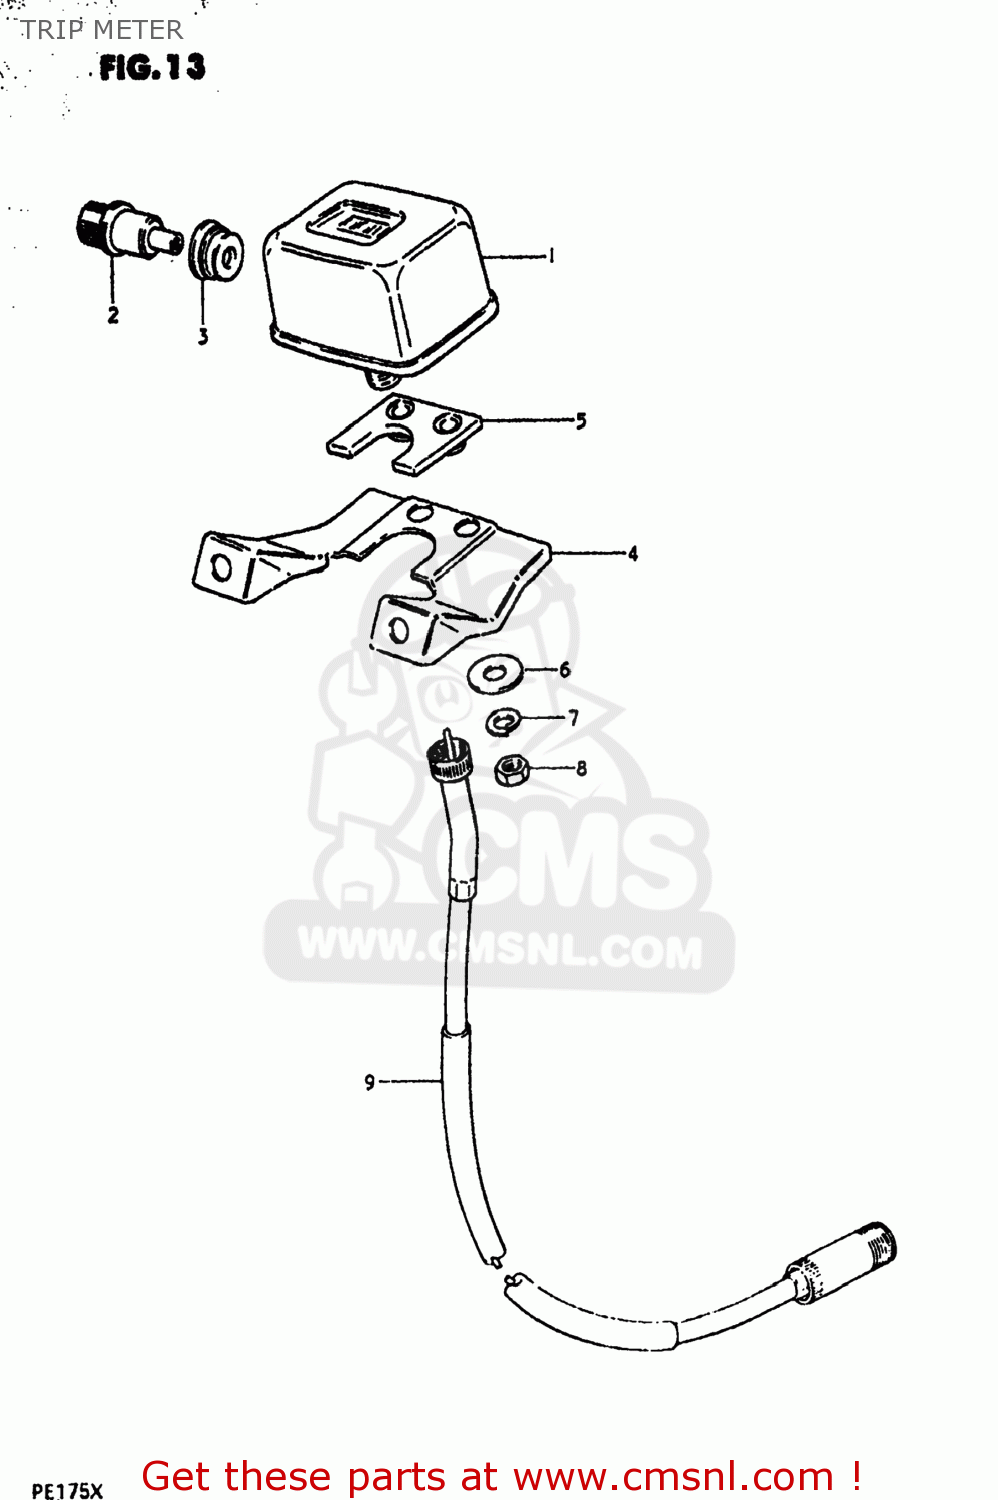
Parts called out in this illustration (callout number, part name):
1	TRIP METER
2	KNOB,TRIP METER
3	COVER,TRIPMETER KNOB
4	BRACKET,TRIPMETER
5	CUSHION,TRIPMETER
6	WASHER,METER
7	LOCK WASHER
8	NUT
9	CABLE ASSEMBLY,SPEEDOMETER
